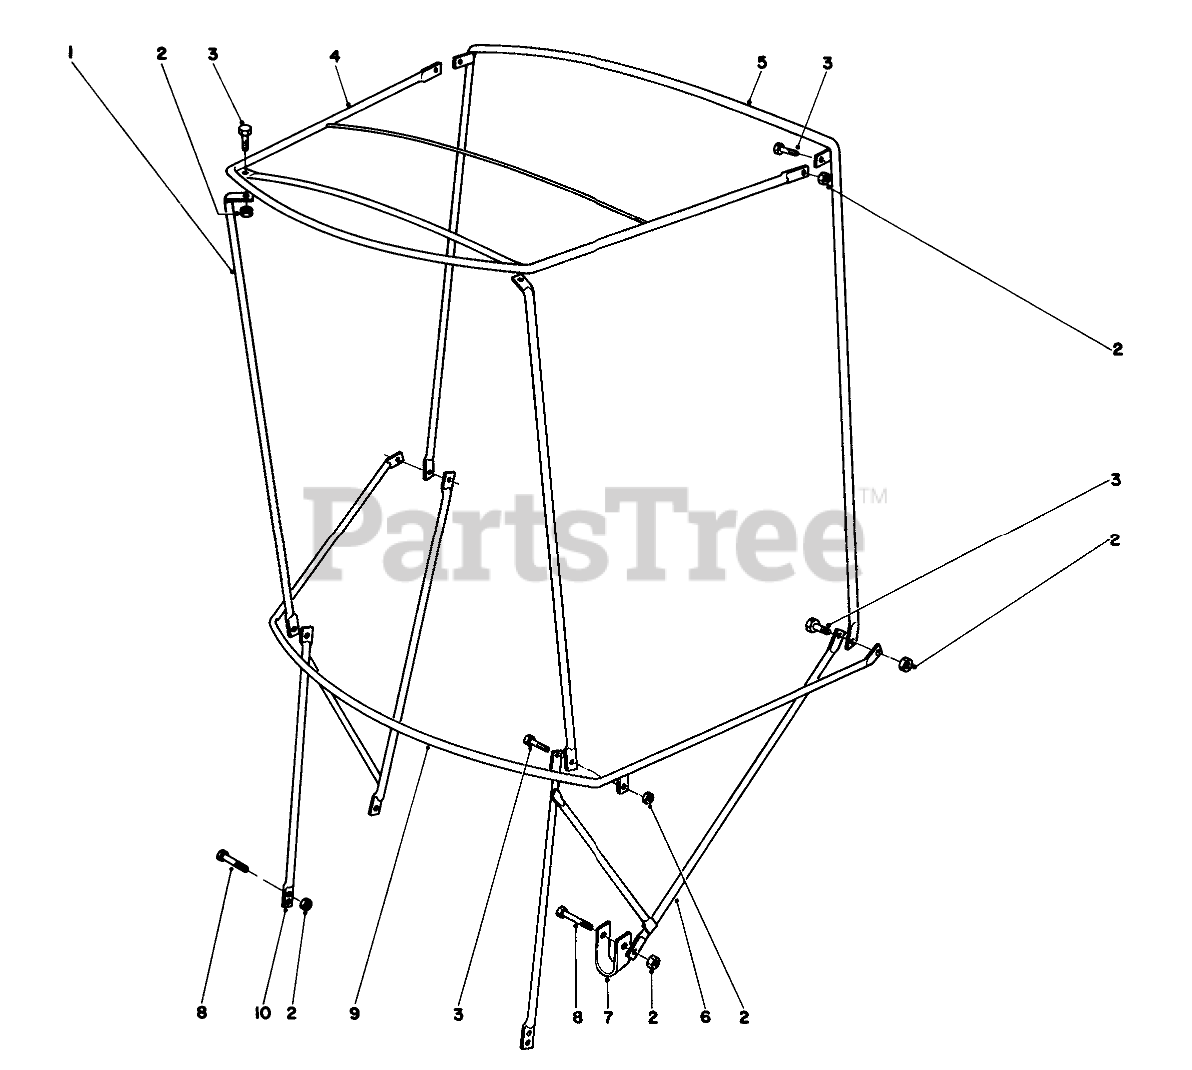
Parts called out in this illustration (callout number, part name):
2	NUT-HEX, SIDE DEFORM
3	Bolt
4	FRAME-TOP
5	BOW-VERTICAL, REAR
6	Attaching Bracket
7	U CLAMP
8	SCREW-HH
9	BOW-CURVED
10	Attaching Bracket R.H.
